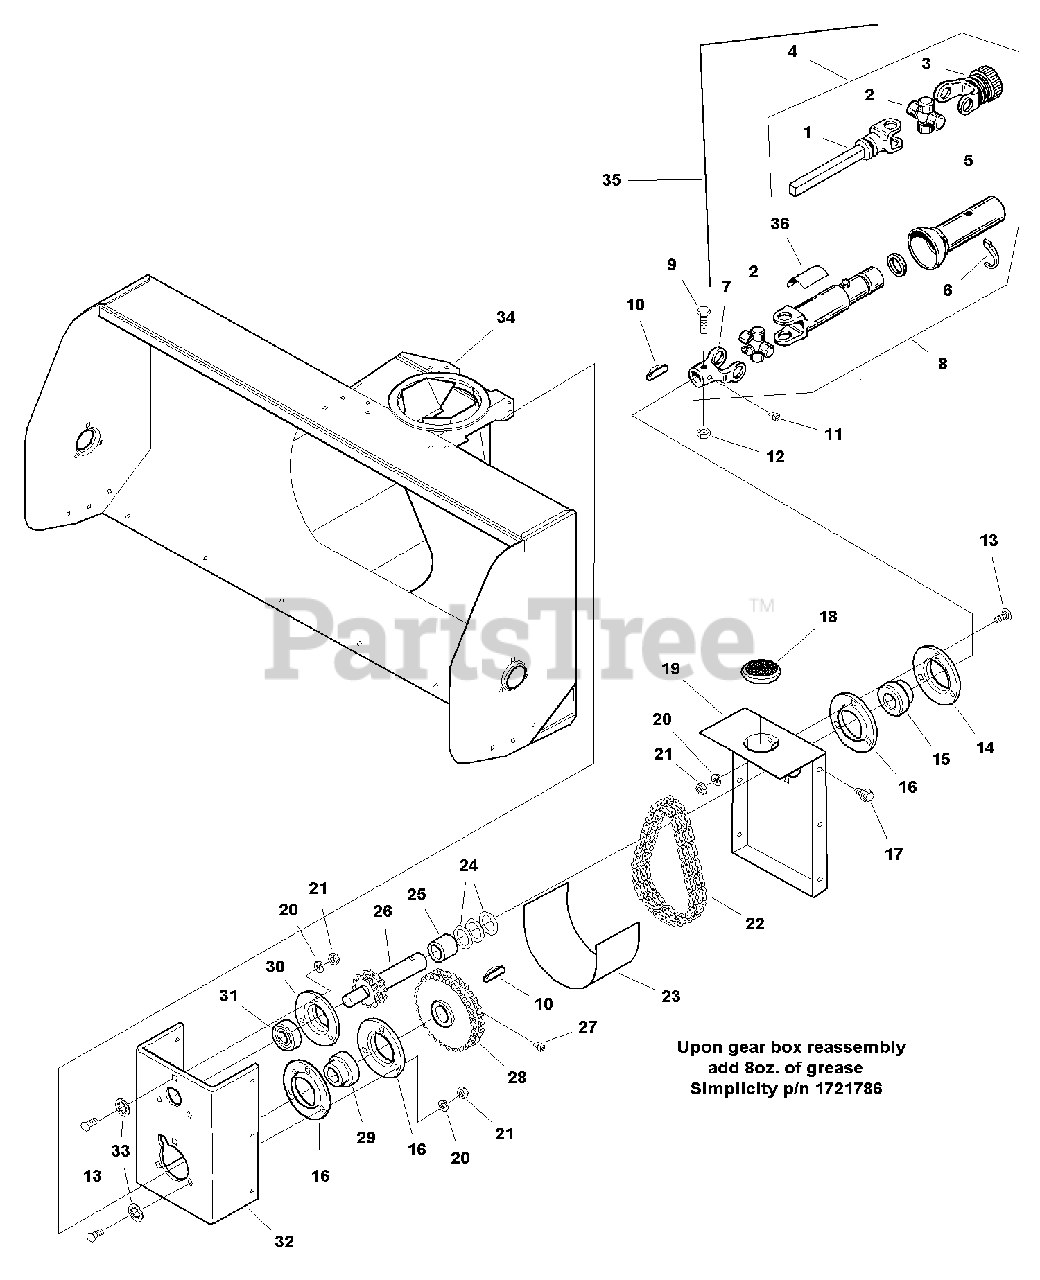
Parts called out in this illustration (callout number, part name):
1	YOKE & SHAFT ASSEMBLY
2	CROSS & BEARING KIT
3	YOKE ASSEMBLY, Spring Lock
4	JOINT & SHAFT ASSEMBLY
5	DRIVE SHAFT INNER GUARD
6	DRIVE SHAFT NYLON REPAIR KIT
8	DRIVE SHAFT JOINT&TUBE ASSEMBLY
9	CAPSCREW, Hex Head, 1/4-20 x 1-7/8
11	SCREW, Set, Hex Socket, Cup Point, 5/16-18 x 3/8
12	NUT, Hex Center Lock, 1/4-20
13	CARRIAGE BOLT, 5/16-18 x 7/8
15	BEARING, Ball
17	SCREW, Hex Head Taptite, 5/16-18 x 3/4
19	COVER
20	LOCKWASHER, 5/16
21	NUT, Hex, 5/16-18
22	CHAIN, Roller, #40 x 20
26	SHAFT & SPROCKETS ASSEMBLY
27	SCREW, Set, Hex, Cup Point
28	SPROCKETS & HUB ASSEMBLY
30	FLANGE, Bearing
33	PUSH NUT, 5/16
34	HOUSING ASSEMBLY
35	SHAFT ASSEMBLY (includes ref. nos. 1-3, 5-7)
36	DECAL, Warning, Rotating Drive Shaft
